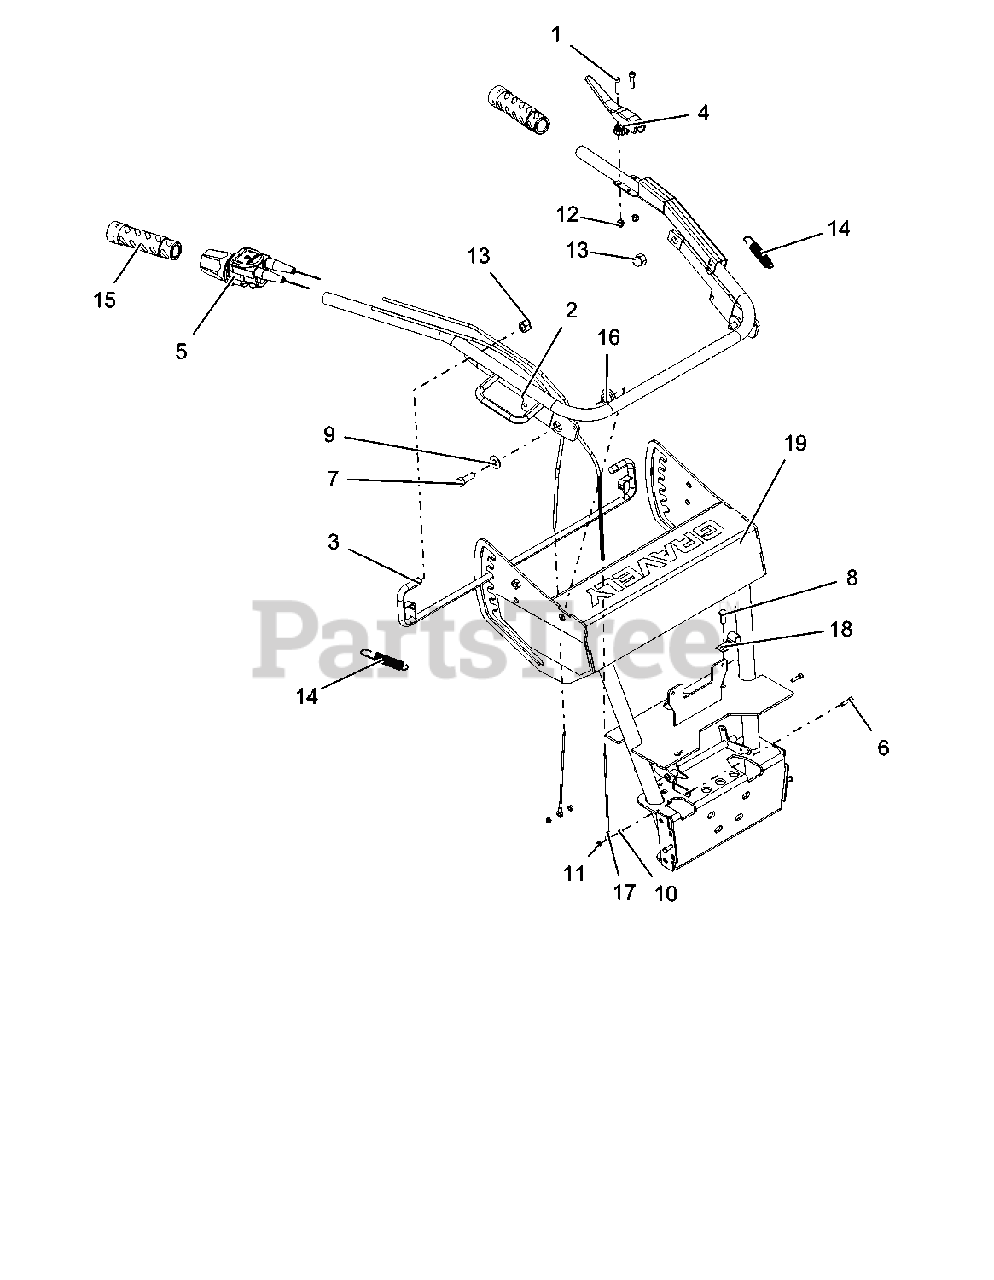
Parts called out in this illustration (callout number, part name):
1	SCR, SKH M6-1 X 25 GR10.9 CKF
2	WLDMT, HANDLEBAR ADJUSTABLE (BLACK)
3	ROD, WLDMT HEIGHT CONTROL
4	ASM, LEVER OP PRESENCE
5	CONTROL, GROUP RAPID
6	SCR, SKH M5-.8 X 20 GR12.9 ROHS
7	BLT, HEX M10-1.5X30 GR8.8 ZC120
8	BLT, HEX M8-1.25X20 GR8.8 ZC120
9	WSHR-FL-STL .438X1.00X.083 ZC120
10	NUT, HEX M5-0.8 GR 8.8 ZC120
11	NUT, LK-NYL M5-0.8 GR8.8 ZC120
12	NUT, LK-NYL M6-1.0 GR8.8 ZC120
13	NUT, ACORN-M12-1.75 BLACK ZINC
14	SPRG, EXTENSION .063 X .653 X 2.755
15	HANDLE RUBBER
16	BSHG, STEP .413X.776X1.25X.413
17	ASM, CABLE SPEED CONTROL
18	P-CLIP, .500 INSULATED
19	ASM, STEERING PIVOT W/DECALS
